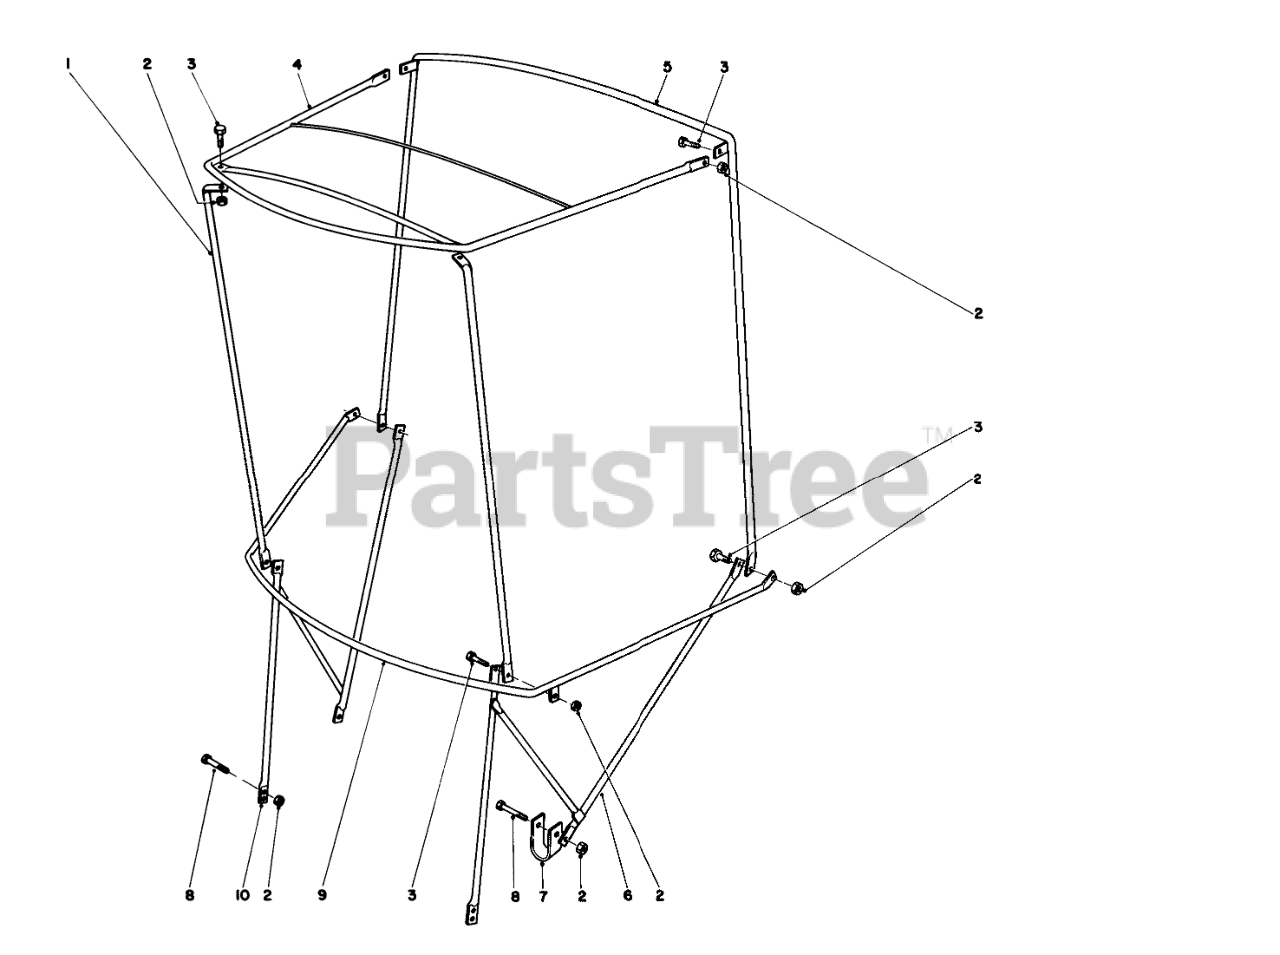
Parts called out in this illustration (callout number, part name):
2	NUT-HEX, SIDE DEFORM
3	SCREW-HH
4	FRAME-TOP
5	BOW-VERTICAL, REAR
6	ATTACHING BRKT L
7	U CLAMP
8	SCREW-HH
9	BOW-CURVED
10	ATTACHING BRKT R
